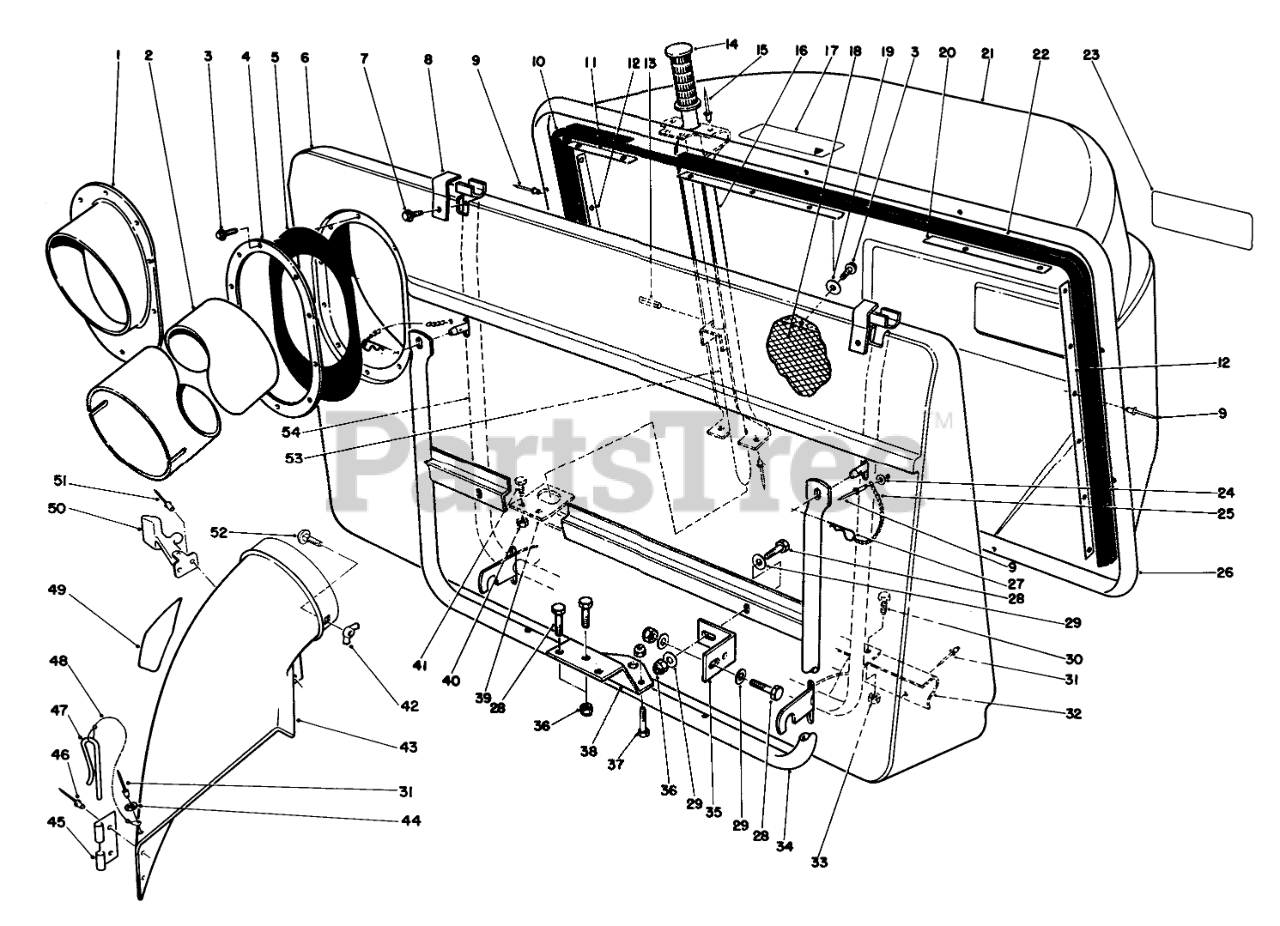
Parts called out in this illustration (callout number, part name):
1	DUCT ADAPTER
2	TUBE(ROUND&LONG)
3	SCREW-HWHTF
4	RING-RETAINING
5	RING-RETAINER, RUBBER
6	Bag Front
7	SCREW-HWH
8	RETNR PIVOT BRKT
10	RH BAG SEAL
11	RETNR TOP EXT.
12	BAG RETNR EXT.
13	PIN-ROLL
16	DUMP HDLE CHANL WA
17	Decal Warning
18	Screen Bag
19	WASHER-FLAT
20	EXTRUSION BAG RETAINER
21	REAR GRASS BASKET
22	Seal-Bag LH.
23	EASY EMPTY BAG DECAL
24	WASHER
25	10 LINK CHAIN W/O HOOK
26	BAG SUPT ASM FRM
27	PIN-HAIR
28	SCREW-HH
29	WASHER-PLAIN
30	SCREW-HH
31	RIVET-BLIND
32	FRAME SUPT BRKT B
33	NUT-LOCK, CONE
34	BAG SUPPORT WA
35	MTG BRACKET
36	NUT-LOCK, NI
37	SCREW-HH
38	MTG PLATE B
39	Hanger-Frame Lower
40	NUT-LOCK, CONE
41	SCREW-HH
42	NUT-WING SPECL
43	Chute Assy. (Incl. Ref. #31 & 44-51)
44	WASHER-PLAIN
45	BRACKET-MOUNTING, CHUTE
46	RIVET-BLIND
47	PIN-LOCKING, CHUTE
48	LANYARD
49	DECAL-DANGER
50	Latch-38"
51	RIVET-POP
52	BOLT-CARR
53	DUMP HANDLE ASM
54	Bag Frame
